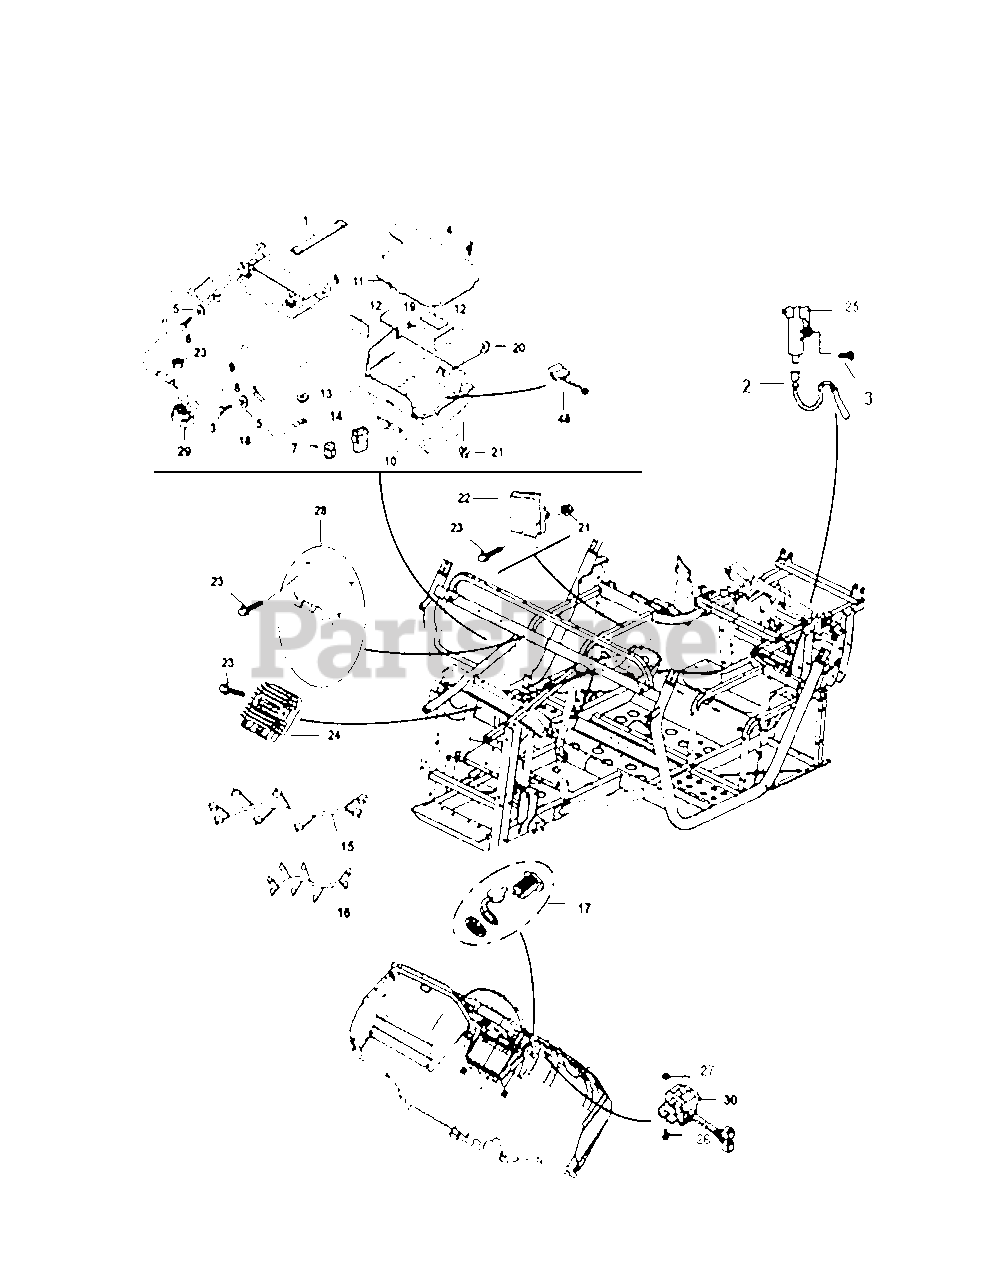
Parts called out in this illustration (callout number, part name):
1	Rubber Latch II
2	Connecting Cable, Ignition Coil(EFI Engine)
3	Hexagon Flange Bolt M6X40
4	Bolt M6×20
5	Cushion 6.5×11.5×1
6	Positive Cable, Battery
7	Flasher
8	Starting Relay
9	Battery -T
10	Battery Box
11	Battery Mounting Cap
12	Battery Cushion
13	Spring Washer -6
14	Main Relay
15	Main Cables
16	EFI Cable Assy(EFI Engine)
17	DC Socket
18	Negative Cable, Battery
19	Hexagon Flange Bolt M6×16
20	Washer6×18×1.6
21	Hexagon Flange Nut M6
22	ECU Controller Assy(EFI Engine)
23	Hexagon Flange Bolt M6×20
24	Voltage Regulator
25	Ignition Coil
26	Cross Large Plate Head Screw M5X16
27	Hexagon flange nut M5
28	Relay Assy (EFI Engine)
29	Starting Relay Rubber Coat
30	2WD/ 4WD Switch
31	Hexagon flange nut M5
32	Cross Large Plate Head Screw M5×16
33	Ignition Coil
